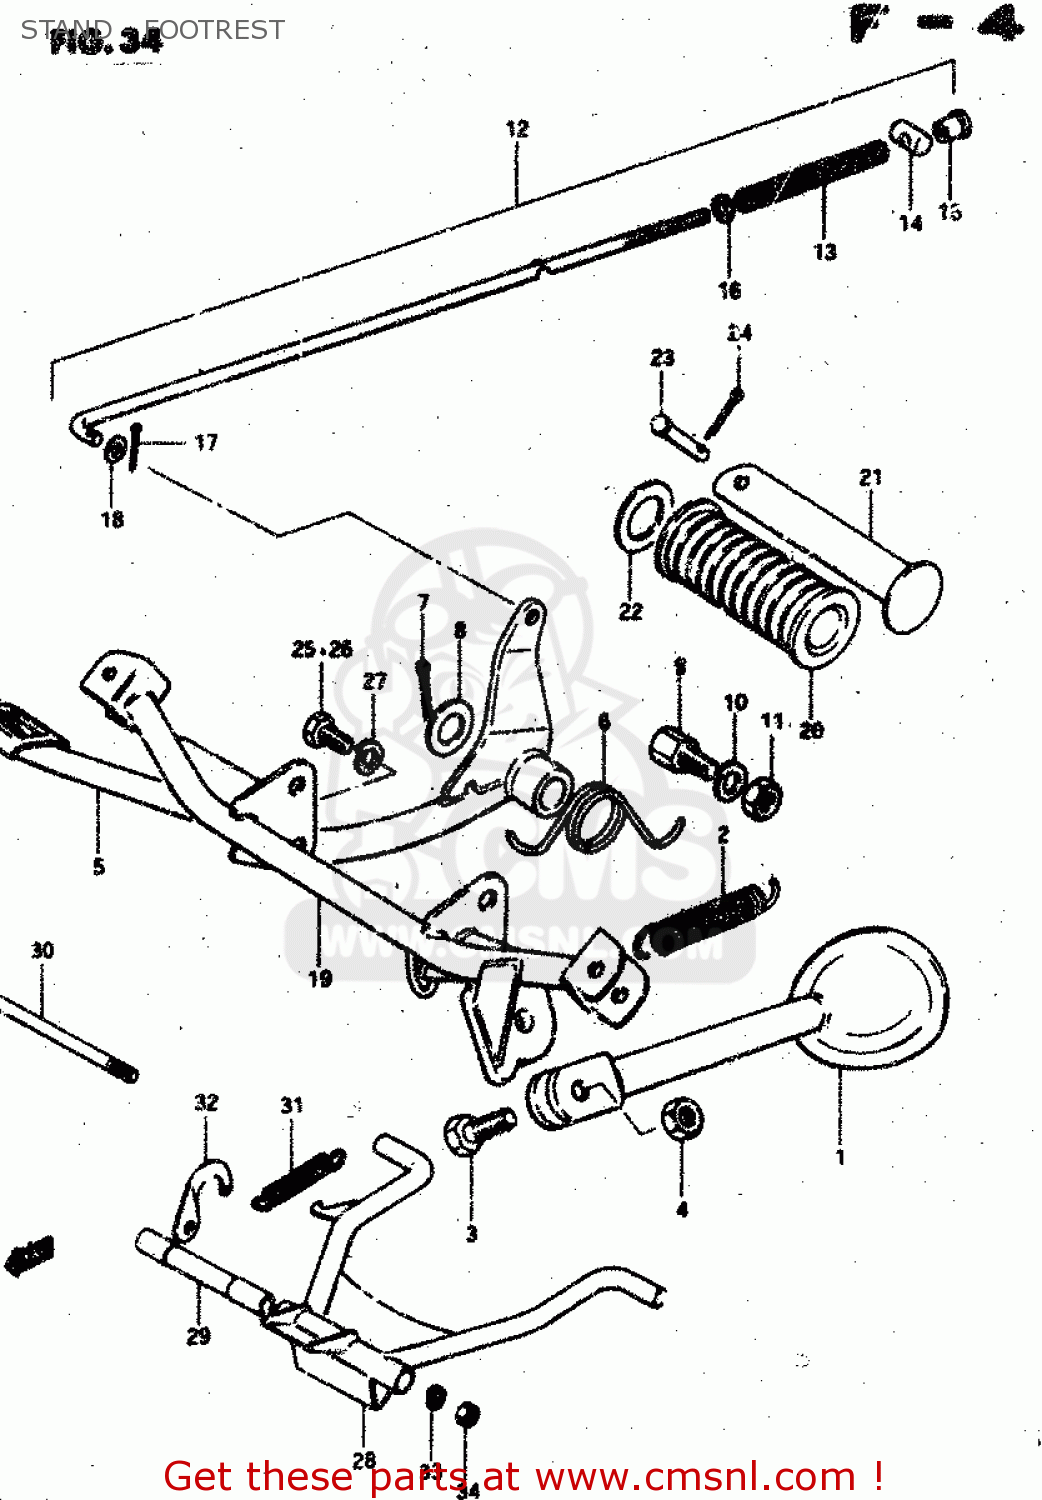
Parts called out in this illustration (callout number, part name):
1	STNAD, PROP
2	SPRING
3	BOLT
4	NUT
5	PEDAL, BRAKE
6	SPRING
7	COTTER PIN
8	WASHER(15.5X26X2.3)
9	BOLT 10X20
10	LOCK WASHER
11	NUT
12	ROD ASSY,RR BRAKE
13	SPRING
14	PIN(11X18)
15	NUT (6MM)
16	WASHER
17	PIN 20X20
18	WASHER
19	BAR, FRONT FOOTREST
20	RUBBER,PILLION FOOTREST
21	BAR,FOOTREST RUBBER
22	WASHER (19.5X32X2)
23	PIN
24	PIN 20X20
25	BOLT
26	BOLT
27	LOCK WASHER
28	STAND, CENTER
29	SPACER
30	BOLT
31	SPRING
32	HOOK,CENTER STAND SPRING
33	LOCK WASHER
34	NUT
